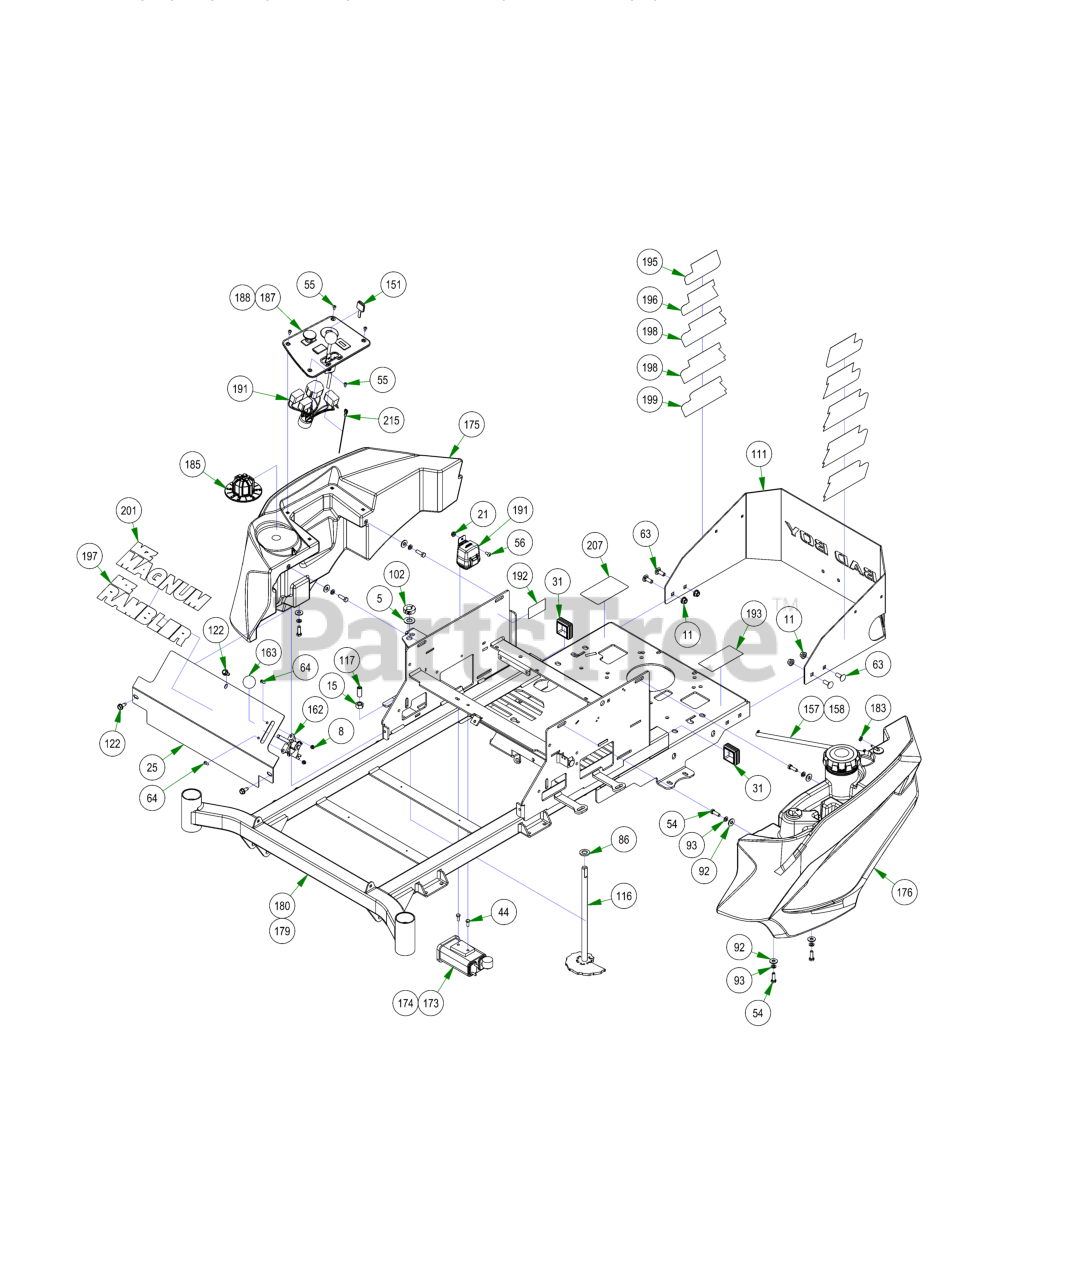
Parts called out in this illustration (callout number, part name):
5	.625 ID x 1.250 OD x .062 THK F/W Nylon
8	10-24 NYLON INSERT LOCKNUT ZINC
11	3/8-16 NYLON INSERT FLANGE LOCKNUT (GR.F) ZINC
15	1/2-13 HEX NUT ZINC
21	1/4-20 HEX SERRATED FLANGE NUT HARD/ZINC
25	2022 MZ Cooler Cover
31	2X2 Frame Plug
44	M6-1.0 X 16MM DIN 933 HEX TAP BOLT (CL 8.8) ZINC
54	5/16-18 X 1 HEX CAP SCREW (GR.5) ZINC
55	10-32 X 3/8 BUTTON SOCKET CAP SCREW 18-8 STAINLESS
56	1/4-20 X 1/2 BUTTON SOCKET CAP SCREW 18-8 STAINLESS
63	3/8-16 X 1 CARRIAGE BOLT (GR.5) ZINC
64	10-24 X 5/8 BUTTON SOCKET CAP SCREW 18-8 STAINLESS
86	.635 ID X 1.120 OD X .140 THICK FLAT WASHER NYLON
92	5/16 USS FLAT WASHER (7/8 OD) ZINC
93	5/16 SPLIT LOCKWASHER ZINC
102	5/8" Split Collar
111	2022 MZ Rear Plate
116	Deck Height Dial Rod Assembly
117	Dial Rod Plunger
122	5/16-18 X 3/4HEX WASHER SLOT (F) TCS ZINC
151	Ignition Key
157	15" Fuel Line Assembly
158	37" Fuel Line Assembly
162	Universal Throttle Head - 2012
163	Throttle Knob
173	MZ Kohler 42" EPA Canister Assembly
174	MZ Kohler EPA Canister Assembly
175	2017 MZ Right Gas Tank
176	2017 MZ Left Gas Tank
179	2022 MZ/ZT 54"-60" Frame
180	2022 MZ/ZT 42"-48" Frame
183	3/16 Vinyl Clamp
185	MZ/ZT Deck Height Dial
187	2017 MZ Control Panel Assembly
188	2019 ZT/Maverick Control Panel Assembly
191	Wiring Harness
192	ANSI Decal BMZ54KT740
193	2022 EPA Build Date Punch Label
195	2018 MZ 541cc Back Plate Cluster
196	2018 MZ 725cc Back Plate Cluster
197	2022 Rambler Front Decal
198	2018 Magnum 725cc Back Plate Cluster
199	2018 Magnum 726cc Back Plate Cluster
201	2017 Magnum Cooler Cover Decal
207	Pump Belt Route Decal-Pump Plate
215	2017 MZ/ZT/MAV Tach Wire Assy
